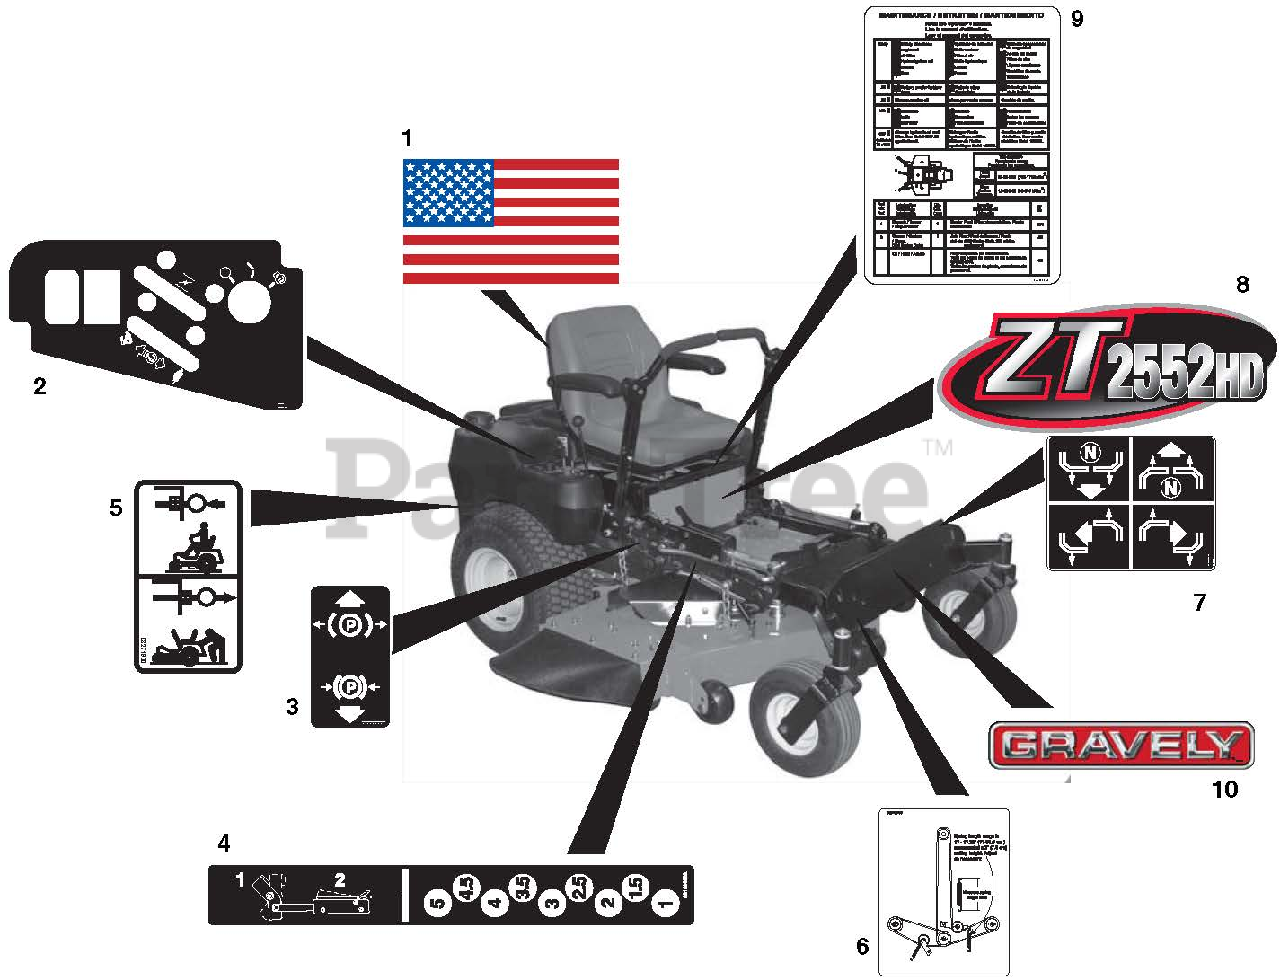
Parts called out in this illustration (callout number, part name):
1	Decal, American Flag
2	Decal, Control Panel
3	Decal, Parking Brake Lever
4	Decal, Height of Cut
5	Decal, Transmission Disconnect
6	Decal, Belt Diagram
7	Decal, Instructional Steering
8	Decal, ZT 2552 HD
8	Decal, ZT 2760 HD
8	Decal, ZT 2344 HD
8	Decal, ZT 2348 HD
8	Decal, ZT 2560 HD
8	Decal, ZT 2660 HD
9	Decal, Maintenance Instructions
10	Decal, 15" Gravely Logo
